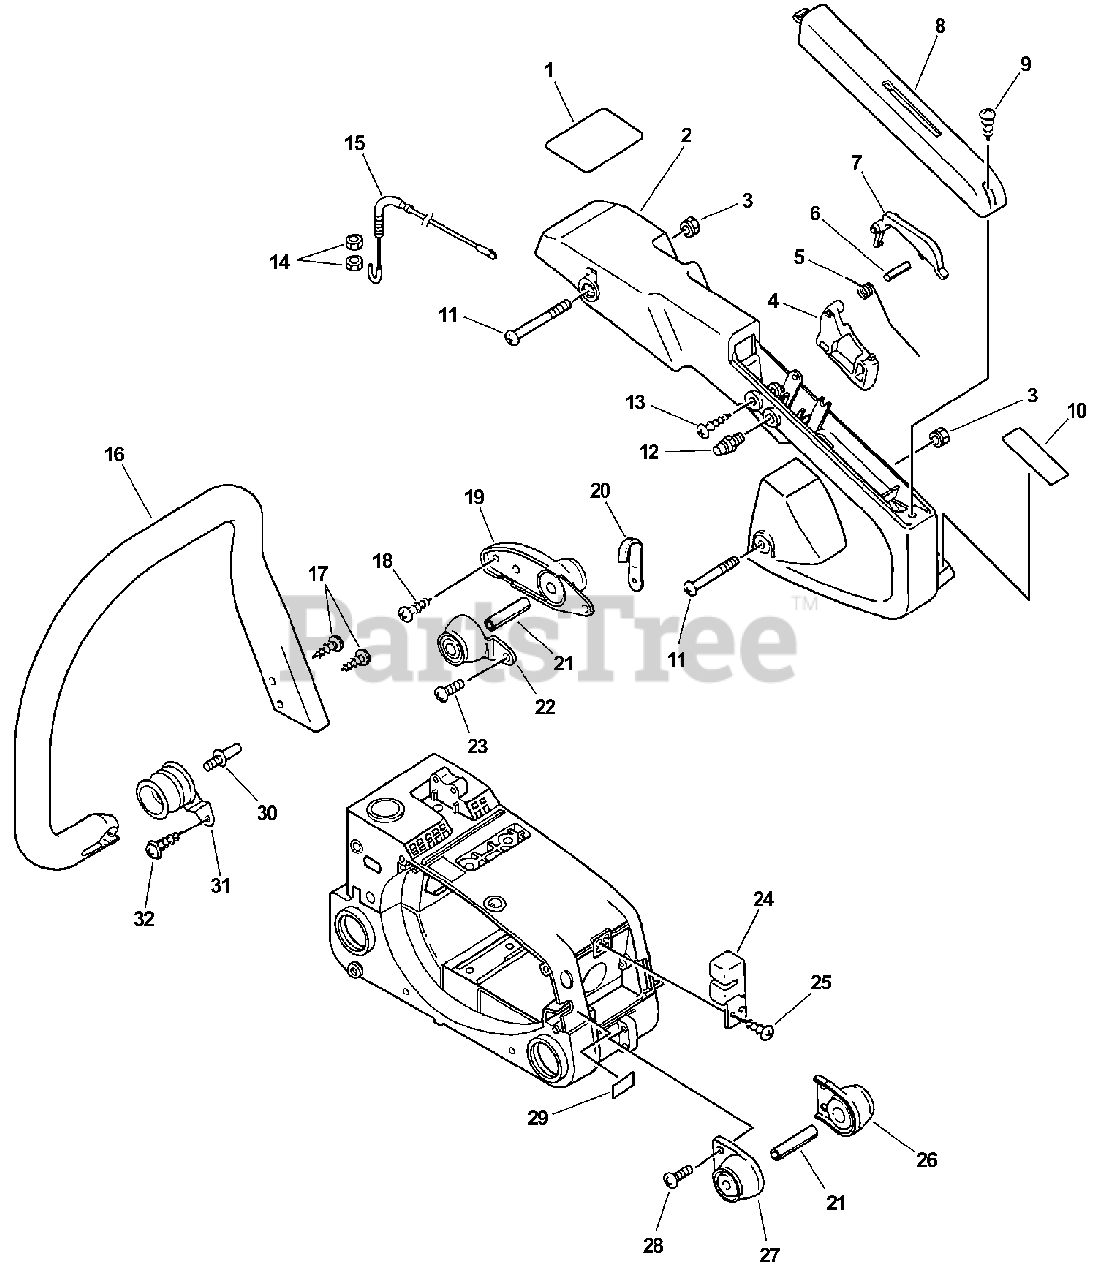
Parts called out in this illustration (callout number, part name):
1	LABEL - KICK BACK
2	HANDLE - REAR
3	NUT - 5 -- FLANGE
4	TRIGGER, THROTTLE
6	ROLLER - 4X19.8
7	LOCKOUT, THROTTLE
8	COVER, HANDLE
9	SCREW - 4X22
10	LABEL - CAUTION
11	SCREW - 5X57
12	LATCH, THROTTLE
13	SCREW - 4X25
15	CABLE, THROTTLE
16	HANDLE - FRONT
17	SCREW - 5X20 -- TAPPING
18	SCREW - 4X10
19	CUSHION - UPPER
21	COLLAR - 6
22	CUSHION - UPPER
23	SCREW - 4X10
25	SCREW - 4X14
26	CUSHION - LOWER
27	CUSHION - LOWER
28	SCREW - 4X14
29	LABEL - STOP
32	SCREW - 4X16
